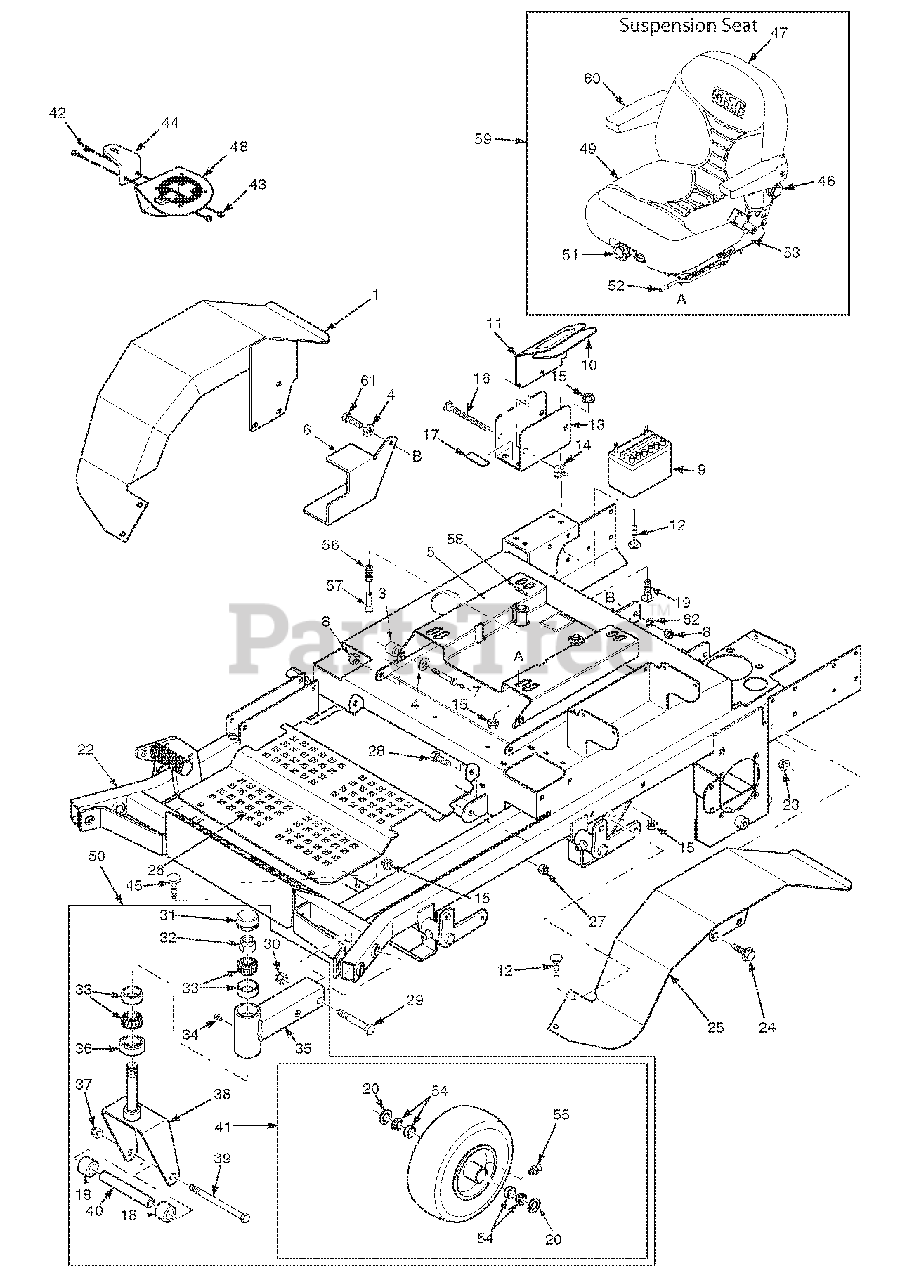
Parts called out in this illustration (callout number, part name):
1	Fender Weldment, RH
2	Bolt, Hex Hd., 5/16-18 x 1, Zinc
3	Spacer
4	Flatwasher, 3/8 (.391 x .938 x .105")
5	Seat Plate Weldment
6	Guard, Fuel Line
7	Bolt, Hex Hd. 3/8-16 x 2.0"
8	Nut, Elastic Stop 3/8-16
9	Battery (not available. through Scag)
10	Pad, Battery Cover
11	Cover, Battery
12	Bolt, Carriage 5/16-18 x 3/4"
13	Plate, Battery Box
14	Wing Nut, 1/4-20 x 3/4"
15	Nut, Hex Serr. Flng. 5/16-18
16	Bolt, Carriage 1/4-20 x 6"
17	Rubber Pad
18	Spacer, Caster Wheel
19	Bolt, Carriage 5/16-18 x 1"
21	Locknut, 3/8-16, Elastic Stop
22	Main Frame
23	Nut, Hex Serr. Flng. 3/8-16
24	Screw, Hex Serr. Flng. 3/8-16 x 1"
25	Fender Weldment, LH
26	Foot Plate
27	Nut, Hex Elastic Stop 3/8-16
28	Bolt, Hex Hd. 3/8-16 x 1"
29	Bolt, Hex Hd. 5/8-11 x 4"
29	Bolt, Hex Hd. 5/8-11 x 4-1/4"
30	Nut, Hex Elastic Stop 5/8-11
31	Cap, Grease
32	Nut, Hex Elastic Stop 1.0-14
33	Bearing w/Race
34	Plug, 1/4-28 THD Form
35	Extension Weldment, Caster 61V LH
35	Extension Weldment, Caster 61V RH
36	Seal, 2.00" O.D. x 1.625" Bore
37	Nut, Hex Elastic Stop 1/2-13
38	Yoke Weldment, Caster (61V)
39	Bolt, Hex Hd. 1/2-13 x 9-1/2" (61V)
40	Sleeve, Caster Wheel (61V)
41	Wheel Assy, 61V, 72A
42	Bolt, Hex Hd. 1/4-20 x 3/4"
43	Bolt, Hex Hd. 1/4-20 x 3/4"
44	Mounting Bracket, STT Cup Holder
45	Lumbar Kit
45	Knob Kit
46	Cable, Seat Stop
47	Back Cushion Kit
48	Cup Holder Assembly
49	Seat Drain Kit (Incl. with Seat Cushion)
50	Caster Wheel Assembly (Incl. 31 thru 43) 61V LH
50	Caster Wheel Assembly (Incl. 31 thru 43) 61V RH
51	Weight Adjustment Kit
51	Knob Kit
52	Seat Adjustment, Track Set
53	Shock Absorber Kit
54	Bearing w/Race
55	Grease Fitting
56	Spring, Seat
57	Pin Retainer, Spring
58	Roll Pin, Spring 5/32 x 3/4"
59	Suspension Seat Assembly w/Seat Belt
60	Armrest Only
60	Armrest Assembly Kit, LH
60	Armrest Assembly Kit, RH
61	Bolt, Hex Head 3/8-16 x 1-1/2"
62	Lockwasher, 3/8" Spring
